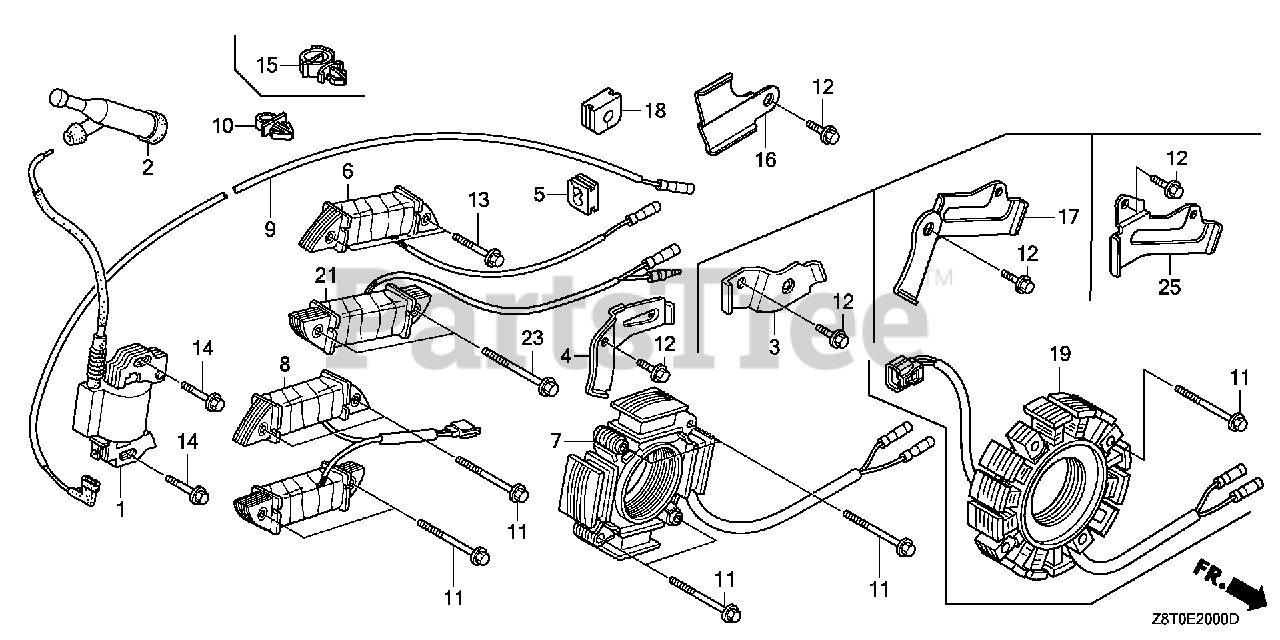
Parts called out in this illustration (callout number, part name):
1	COIL ASSY., IGNITION
2	CAP ASSY., NOISE SUPPRESSOR (NGK Y-EZD)
3	CLAMP, WIRE
5	GROMMET, WIRE
7	COIL ASSY., CHARGE (12V/18A)
9	WIRE, STOP SWITCH (430MM)
11	BOLT, FLANGE (6X40) (CT200)
12	BOLT, FLANGE (6X12) (CT200)
14	BOLT, FLANGE (6X28) (CT200)
15	CLIP, HARNESS
